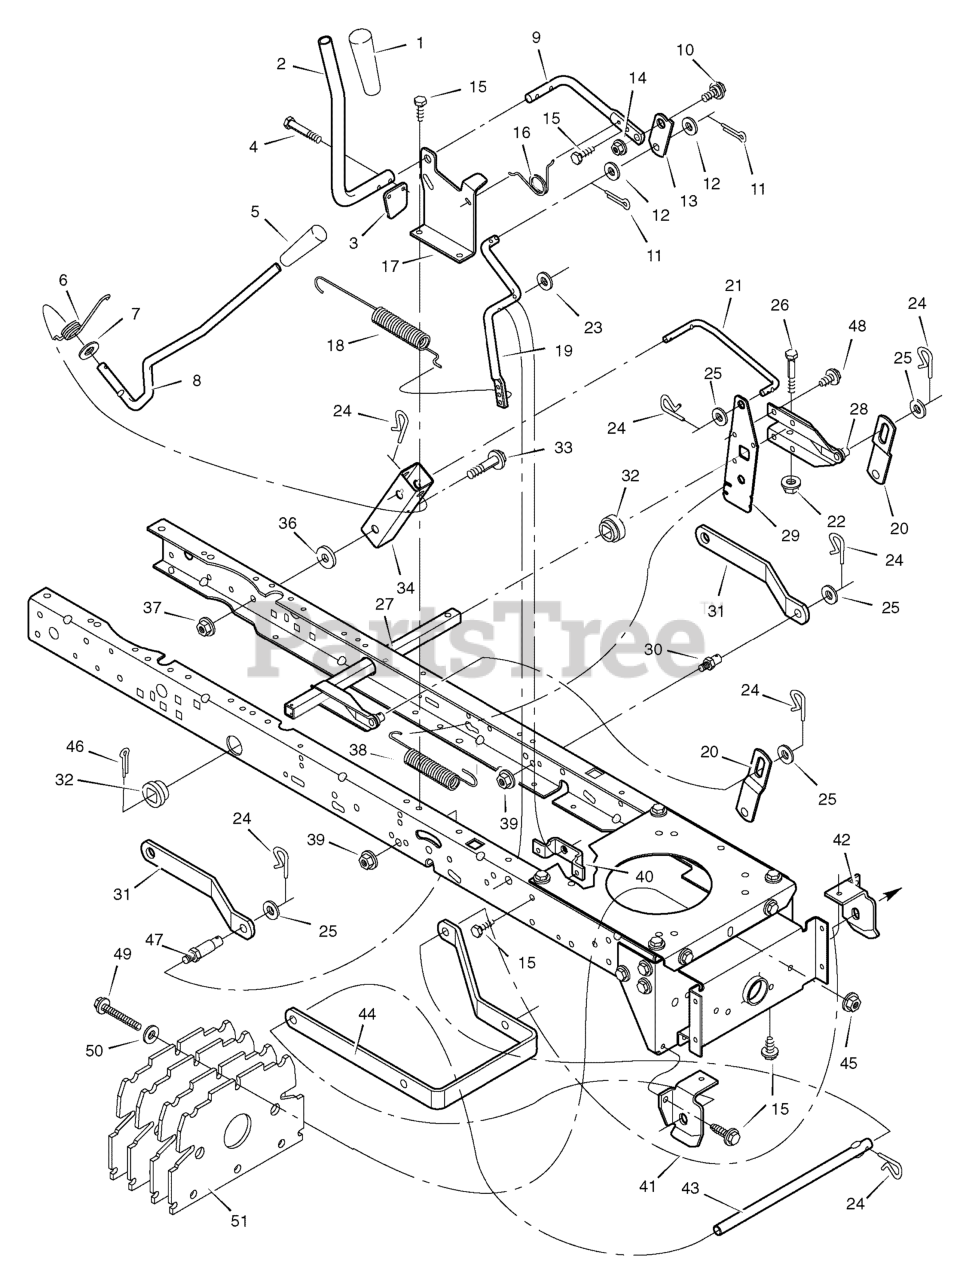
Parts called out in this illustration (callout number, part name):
2	HANDLE, PTO
3	PAD, Switch
4	SCREW, Hex
8	HANDLE, Lift
9	LEVER, PTO
10	BOLT, Shoulder
11	PIN, Cotter
13	LINK, PTO
14	NUT, Flange
17	BRACKET, PTO
19	CRACK, PTO
20	LINK, Lift
21	LINK, Lift Handle
22	NUT, Flange
24	PIN, Hair
26	BOLT, Hex
27	ARM ASSEMBLY, Right Lift
28	LIFTER TUBE ASSEMBLY
29	Plate, Lift Arm
30	PIN
31	BRACKET, Rear Suspension
32	Bushing, Lift Tube
33	BOLT, Shoulder
34	BRACKET, Pivot
37	NUT, Flange
39	NUT, Flange
40	BRACKET, PTO
41	HANGER, Right Deck
42	HANGER, Left Deck
43	ROD, Hanger
44	HANGER, Front
45	NUT, Flange
46	PIN, Cotter
47	PIN, Threaded Shoulder
49	BOLT, Hex
51	PLATE, Weight
